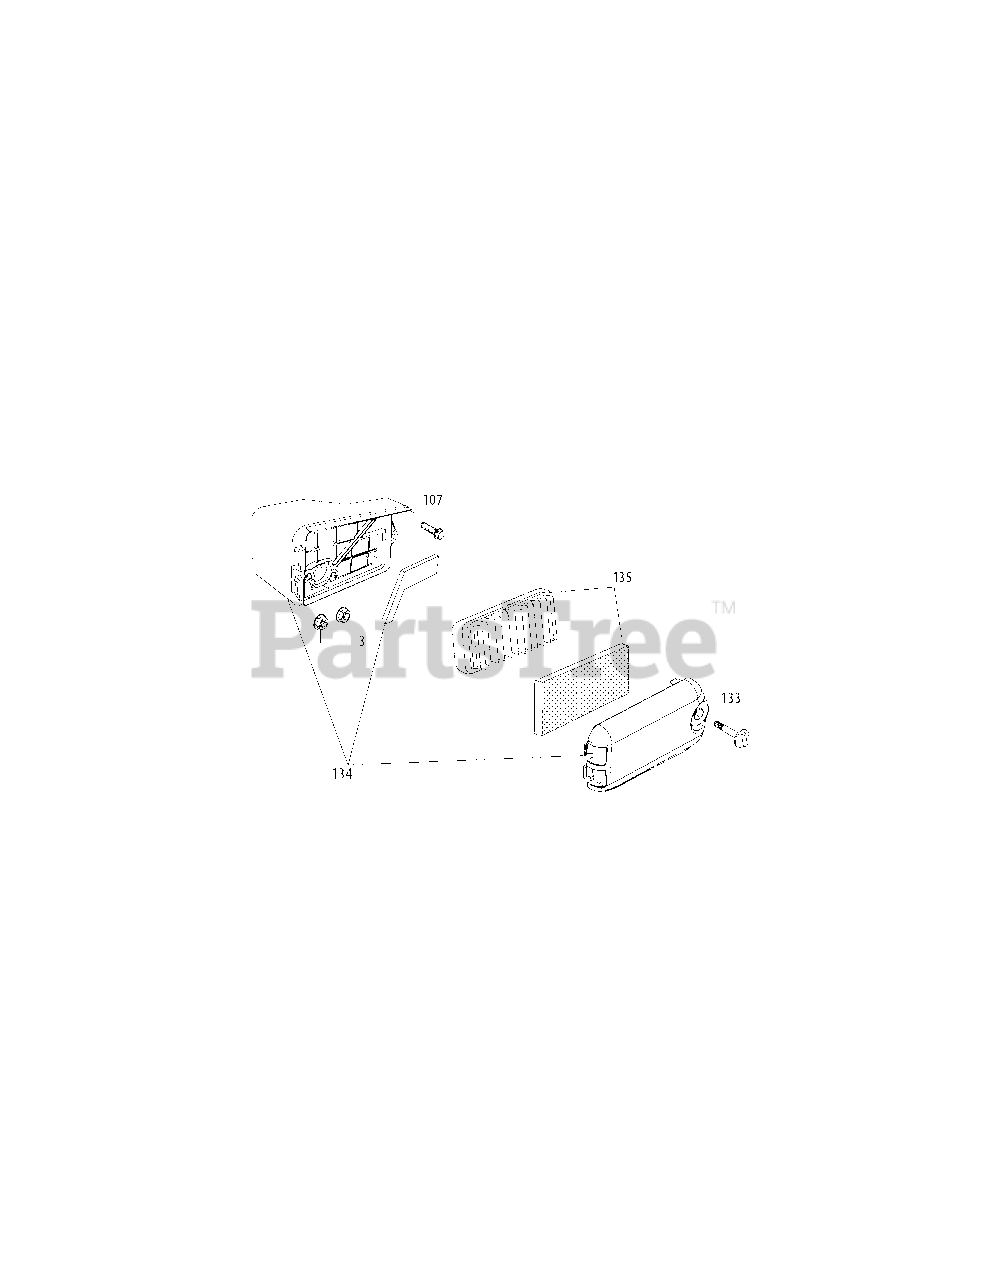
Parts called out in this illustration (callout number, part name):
3	Nut M6 X 10 Mm
107	Bolt M6×35
133	Air Filter Cover Thumb Screw
134	Air Cleaner Housing Assy Comp
135	Air Cleaner Kit
